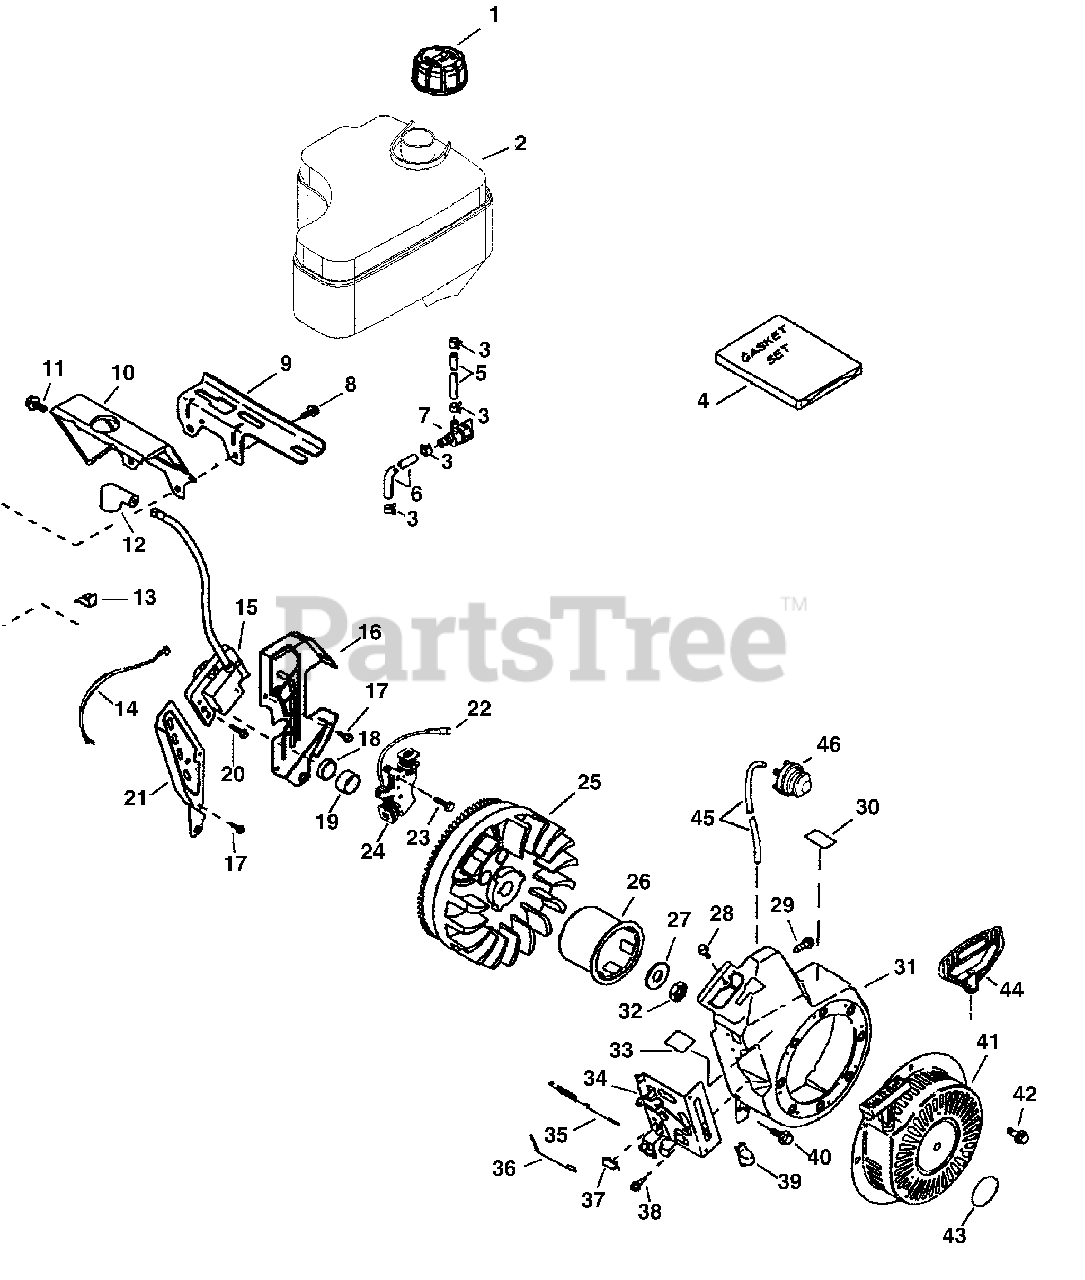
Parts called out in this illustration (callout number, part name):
1	Fuel Cap
2	Fuel Tank
3	Fuel Line Clamp
4	Gasket Set
5	Fuel Line
6	Fuel Line
7	Fuel Shut-Off Valve
8	Screw, 1/4-20 x 7/8"
9	Fuel Tank Bracket
10	Blower Housing Extension
11	Screw, 10-24 x 9/16"
12	Spark Plug Cover
13	Wire Clip
14	Ground Wire
15	Solid State Ignition
16	Air Baffle (Right)
17	Screw, 10-24 x 9/16"
20	Screw, Torx T-15, 15/16"
21	Air Baffle (Left)
23	Screw, 1/4-20 x 3/4"
24	Alternator Coil (18 Watt)
26	Starter Cup
27	Bell Washer
28	Screw, 1/4-20 x 31/64"
29	Screw, 10-32 x 1/2"
30	Lube Decal
31	Blower Housing
32	Flywheel Nut
33	Control Decal
34	Control Bracket
35	Extension Spring
36	Governor Link
38	Screw, 10-32 x 1/2"
39	Control Knob
40	Screw, 1/4-20 x 31/64"
41	Rewind Starter
42	Screw, 1/4-20 x 31/64"
43	Starter Decal
44	Mitten Grip Starter Handle
45	Primer Line
46	Primer Assemblies
